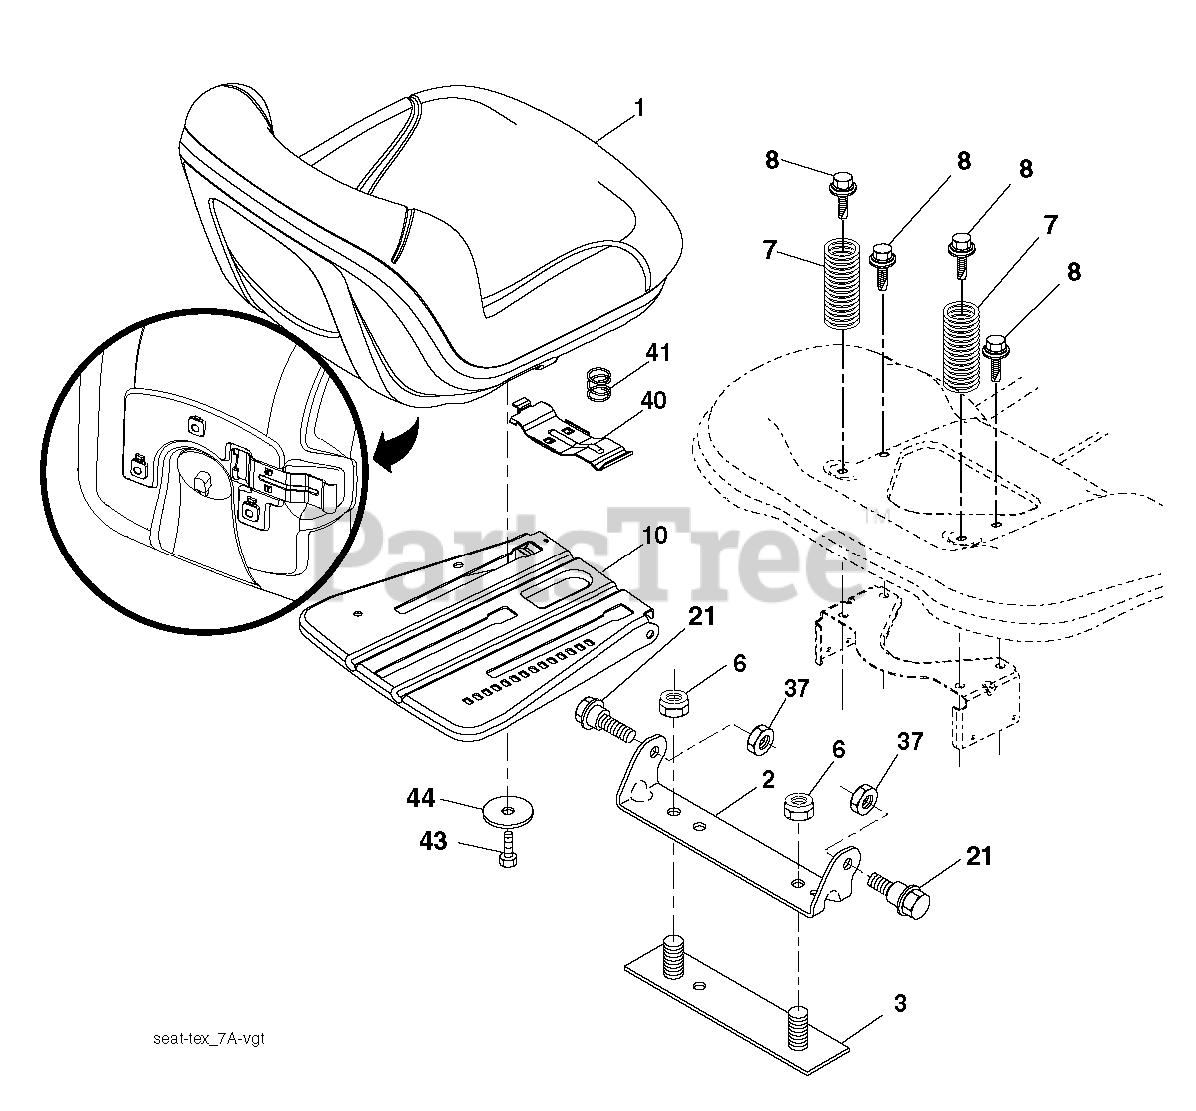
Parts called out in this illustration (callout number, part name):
1	RP SEAT.TH130.GRY.MILSCO.
2	BRKT.PIVOT.FENDER
3	STRAP
6	NUT
7	SPRING COMPRESSION
8	BOLT.5/16-18UNCX3/4 W/SEMS.BLK
10	PAN.ASM.SEAT.3PT
21	BOLT.SHOULDER.5/16-18
37	NUT.71038.31-18.HEX.NYLOCK
40	HANDLE.SLIDE.SEAT.TEX.BLACK
41	SPRING.LATCH.SEAT.TEX
44	WASHER 13/32 X 2-3/8 X 12GA
